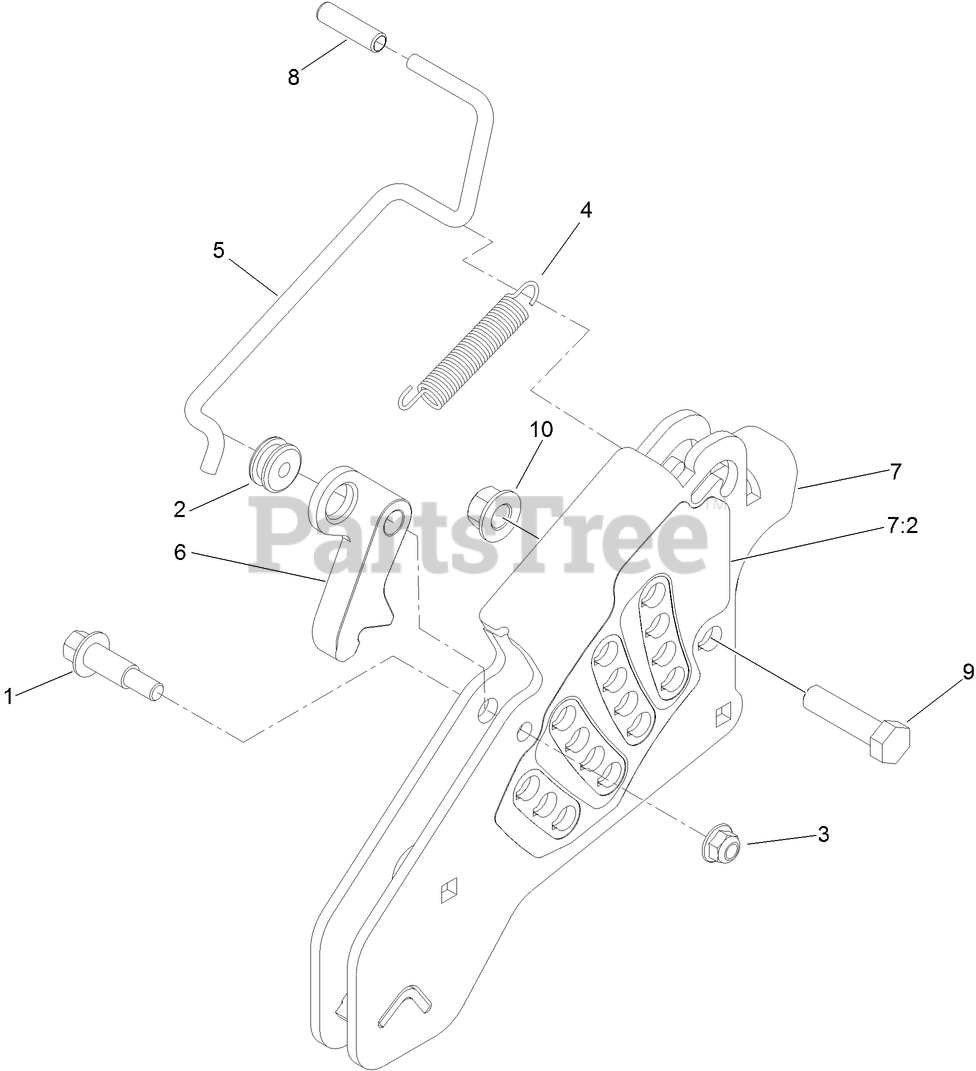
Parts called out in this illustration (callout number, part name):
1	BOLT-SHOULDER
2	GROMMET
3	NUT-HF, NI
4	SPRING-EXTENSION
5	ROD-LOCK, TRANSPORT
6	PAWL-TRANSPORT, HOC
7	HOC PLATE ASM
7:2	DECAL-HOC CE
8	GRIP-LEVER
9	SCREW-HH
10	NUT-LOCK
